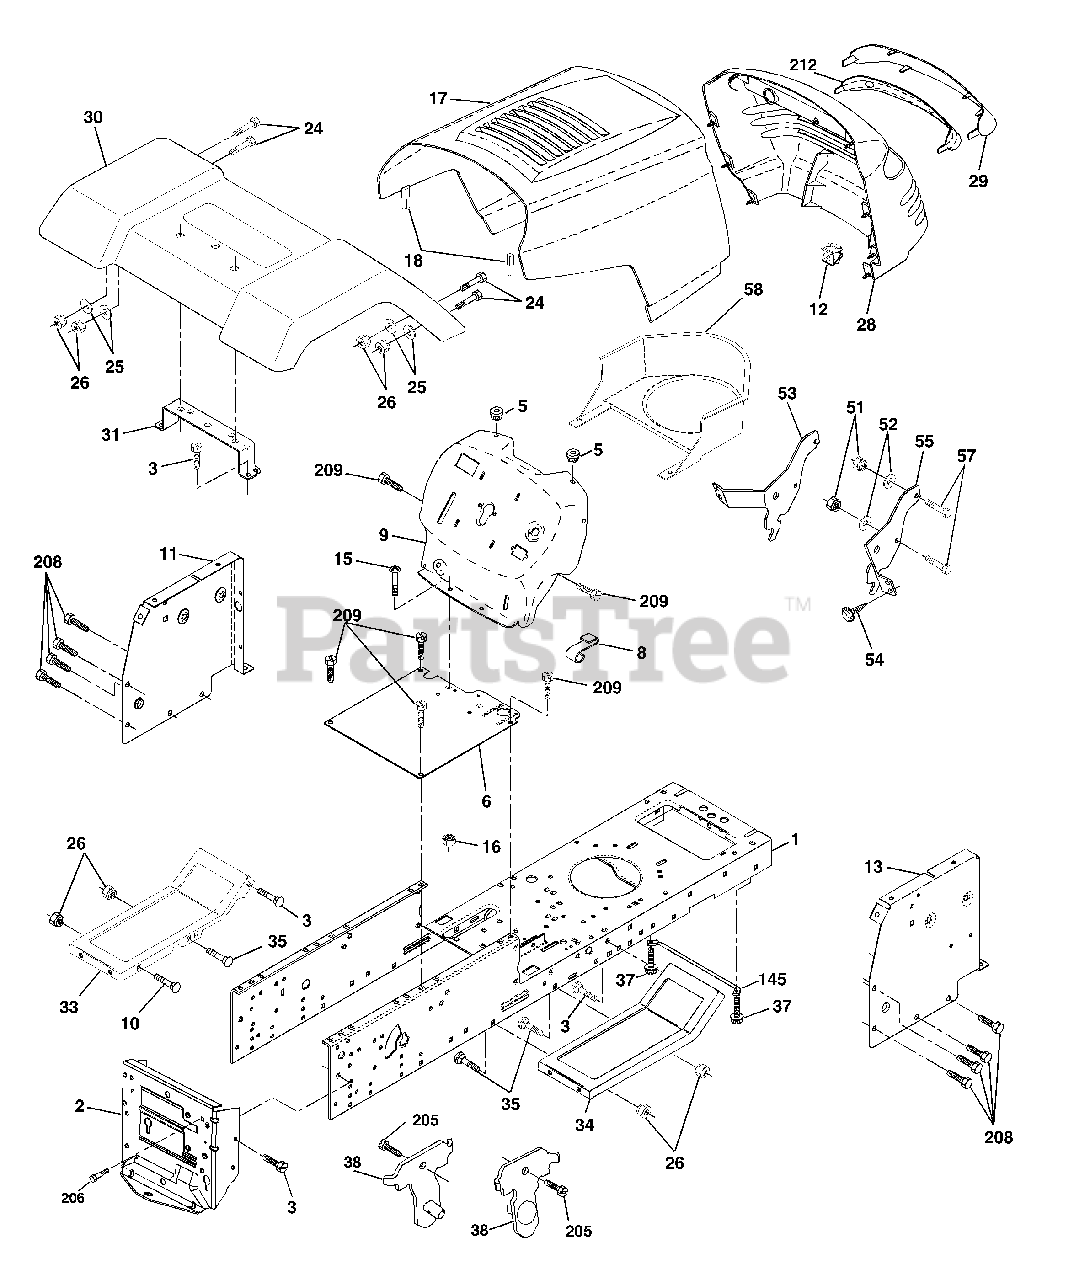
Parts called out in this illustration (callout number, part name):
1	Chassis
2	Drawbar, Stretch
3	Screw 3/8-16 x 3/4
5	Bumper, Hood/Dash
6	Saddle Silkscreen
8	Clip Retainer Slide-On
9	Dash
10	Bolt, Carriage 3/8-16 x 1
11	Panel Dash LH
12	Clip Tinnerman Grille P.L
13	Panel Slkscr Dash RH
15	Screw Mach TRHD 5/16-18uncx3/4
16	Nut Keps 5/16-18 Unc
17	Hood
18	Bumper Hood
24	Bolt Fin Hex 3/8-16unc X 1 Gr. 5
25	Washer 13/32 X 13/16 X 12 Ga
26	Nut Lock Hex w/Ins 3/8-16 Unc
28	Grille/Lens Asm.
29	Lens Grille Private Label
30	Fender
31	Bracket Fender Repl 109873x
33	Footrest Pnt LH
34	Footrest Pnt RH
35	Bolt Rdhd Sht Sqnk 3/8-16 X3/4
37	Screw Thdrol 5/16-18 x 1/2 TYT
38	Bracket Asm. Pivot Mower
51	Nut Lock W/Insert 1/4-20unc
52	Washer 9/32 x 7/8x16 Ga.
53	Bracket Grille Lh
54	Screw Hex 8-18 x 7/8
55	Bracket Grille Rh
57	Bolt Fin Hex 1/4-20 unc x .75
58	Duct Air Engine PL/LT
145	Rod Pivot Chassis/Hood
205	Screw Thdrol 3/8-16 x 1/2
206	Bolt Shoulder 5/16-18
208	Screw Thdrol 3/8-16 x 1/2
209	Screw Hex Wsh Thdrol 3/8-16
212	Insert Lens Reflect
